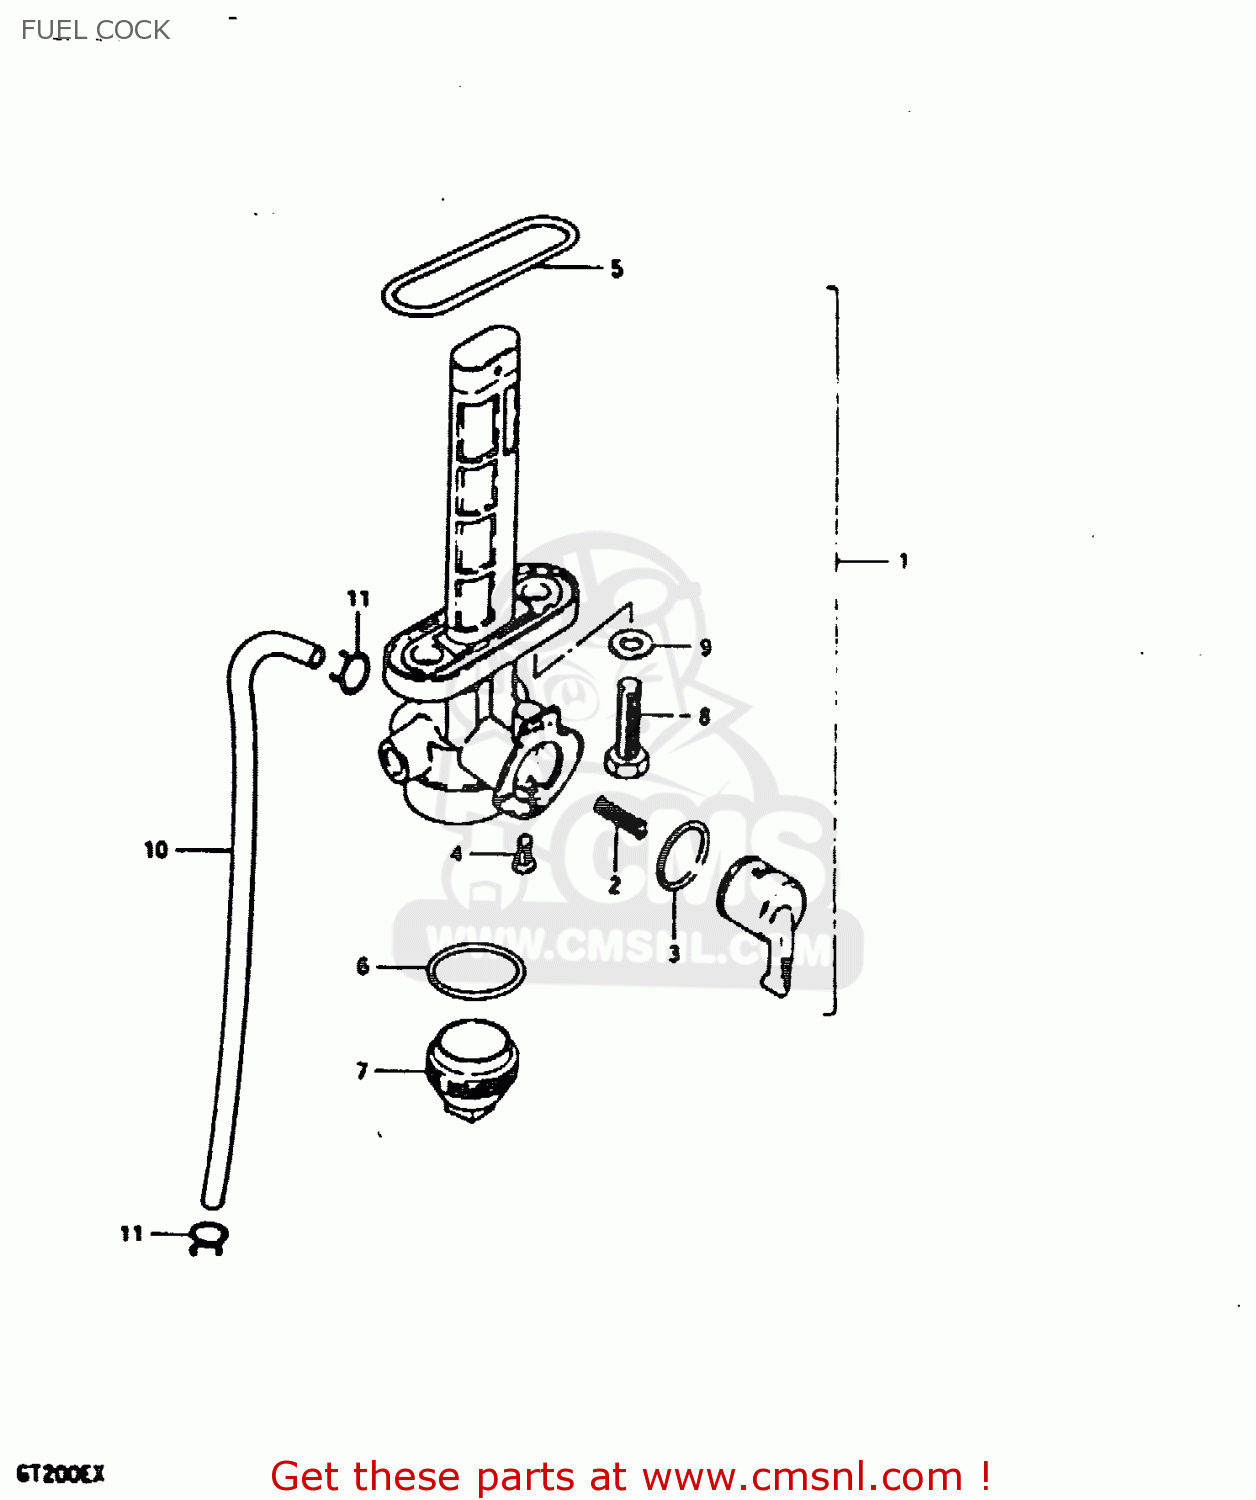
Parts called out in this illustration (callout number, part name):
1	COCK ASSY, FUEL
2	SPRING
3	O-RING
4	SCREW
5	O RING,FUEL COCK
6	GASKET,FILTER (NAS)
7	CUP,STRAINER
8	BOLT(6X20)
9	GASKET
10	HOSE
11	CLIP
